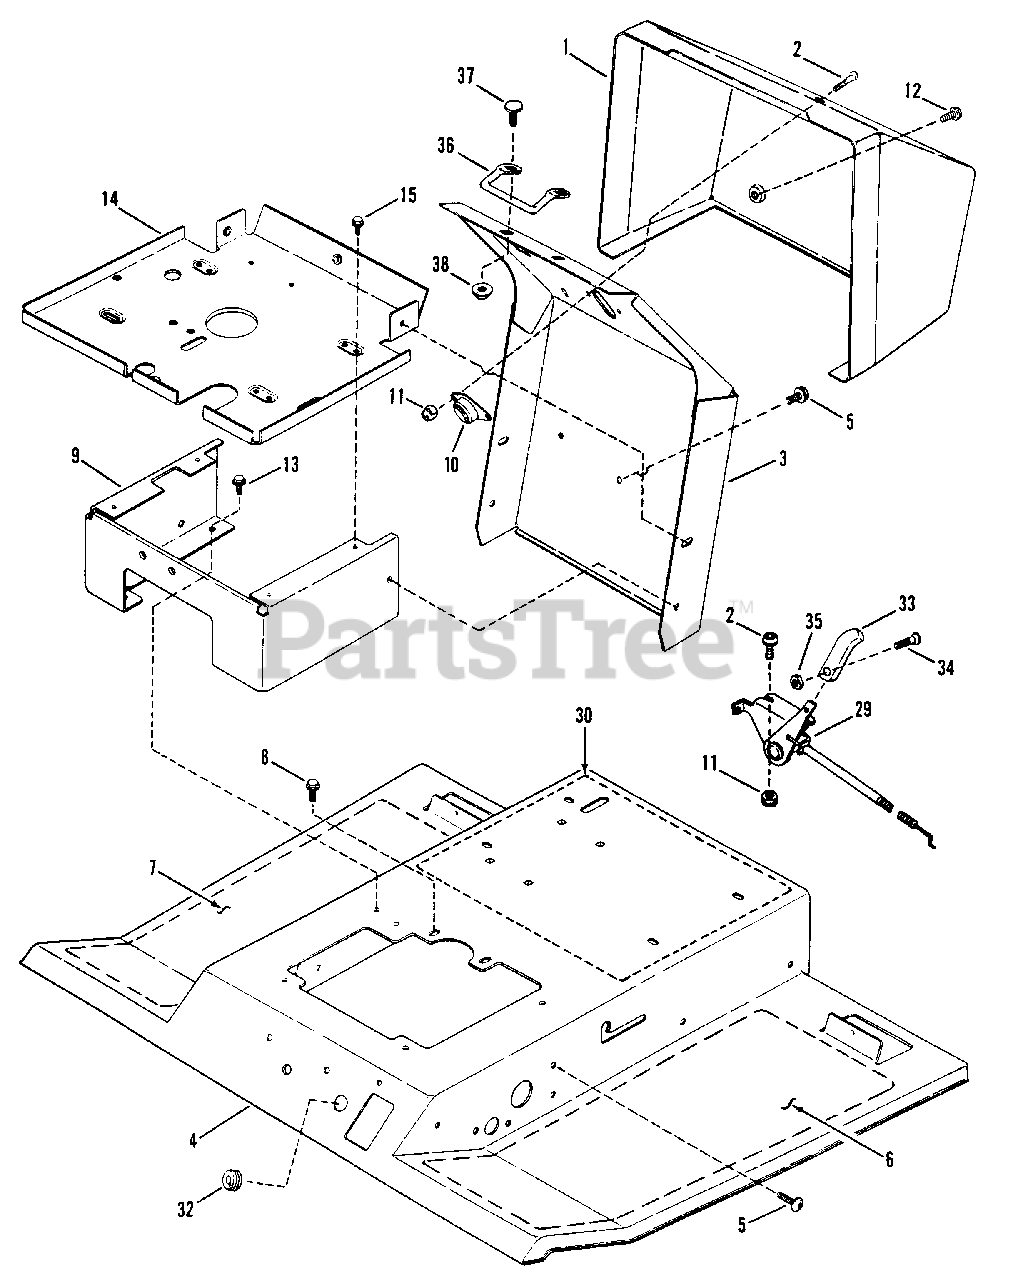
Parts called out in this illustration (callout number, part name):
1	PANEL, Dash
2	SCREW, 1/4-20 x 1" Phillips
3	SUPPORT, Steering Shaft
4	CHANNEL, Foot Rest
5	SCREW, 5/16-18 x 7/8" Torx, S.T.
6	TREAD, Left Side
7	TREAD, Right Side
8	SCREW, 5/16-18 x 5/8" Hex Cap S.T.
9	MOUNT, Fuel Tank/Battery
10	FLANGE ASSM'Y., Steering Shaft
11	NUT, 1/4-20 Hex
12	SCREW, #10-24 x 1/2" Self-Tapping
13	SCREW, 5/16-18 x 1/2" Self-Tapping
14	PLATE, Fuel Tank & Battery Mount
15	SCREW, 1/4-20 x 1/2" Hex Cap, S.T.
29	CONTROL, Throttle
30	DECAL, Caution & Instruction
32	GROMMET, 5/16 I.D. x 1" O.D. Split
33	HANDLE, Throttle Control
34	SCREW, #8-32 x 3/8" Recessed, Fillister Head
35	NUT, #8-32 Hex
36	ROD, Hood Latch
37	BOLT, 1/4-20 x 5/8" Flat Head Carriage
38	NUT, 1/4-20 Hex Flange Lock
